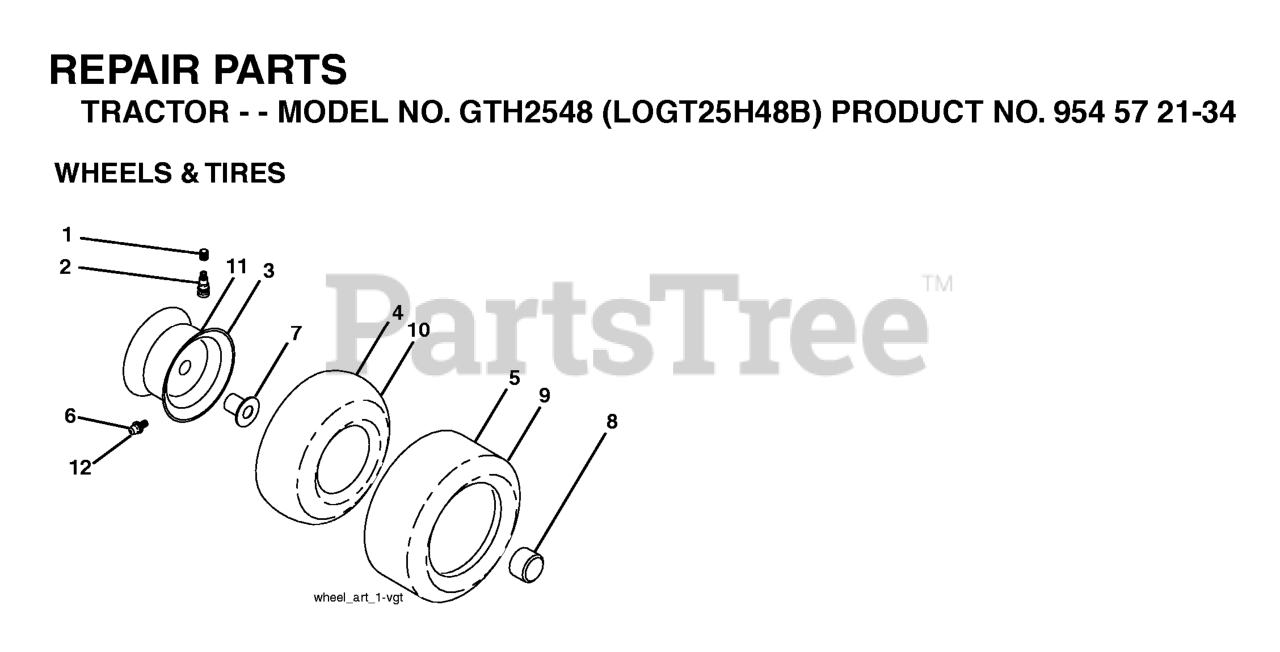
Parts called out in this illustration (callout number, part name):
2	VALVE STEM LT
3	RIM ASSEMBLY, FRONT
4	TUBE.16X6.5/7.5-8
5	TIRE HEAVY DUTY
6	FITTING LT
7	BEARING T
8	CAP, AXLE BLK
9	TIRE HEAVY DUTY
10	TUBE.23X9.5-12
11	RIM.ASM.12X7.REAR.SILVER
12	ZERK FITTING M
